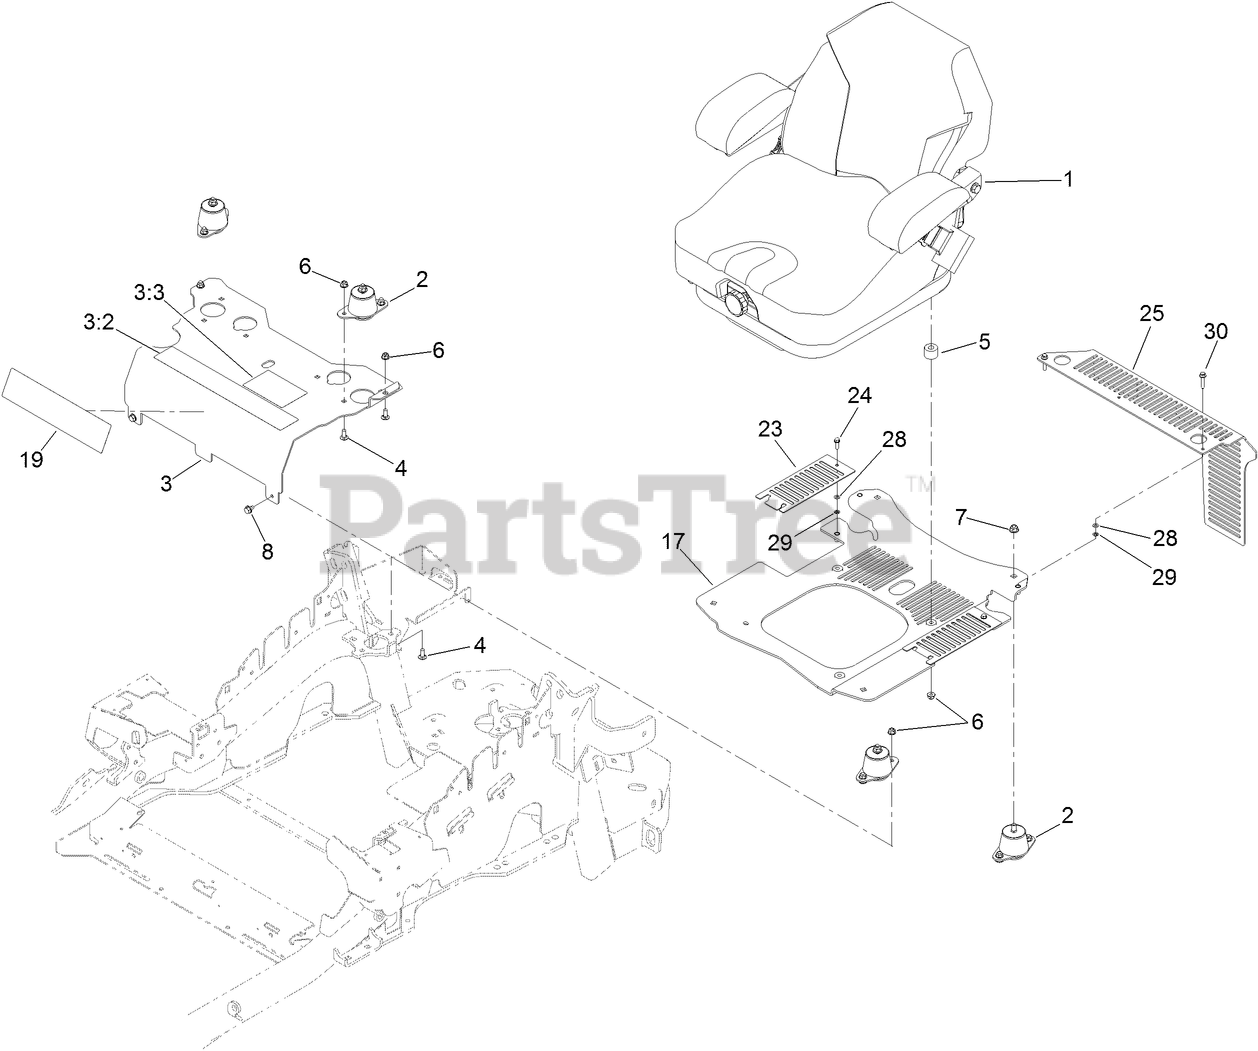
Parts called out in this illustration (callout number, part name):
1	SUSPENSION SEAT ASM
2	ISOLATOR-SEAT
3	MOUNT-SEAT
3:2	DECAL-CONSOLE
3:3	DECAL-SERVICE AID
4	SCREW-CARR
5	SPACER
6	NUT-HF, NI
7	NUT-HF, NI
8	SCREW
17	SEAT BASE ASM
24	SCREW-HWH
25	GUARD-CE
28	WASHER-FLAT
29	NUT-RETAINER
30	SCREW-HHF
